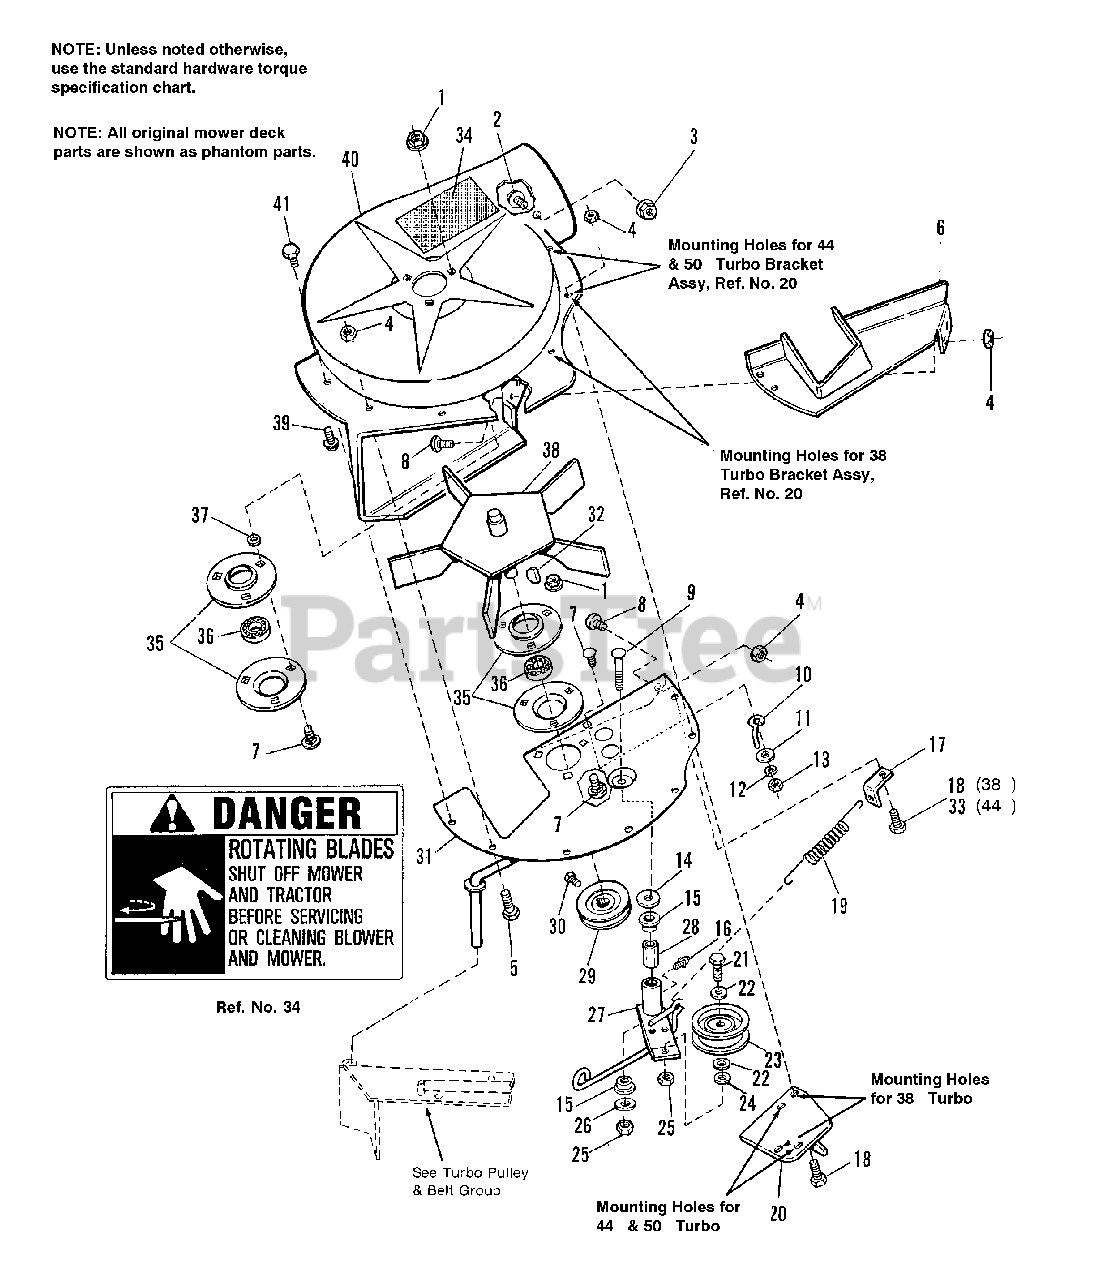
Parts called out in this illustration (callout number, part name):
1	NUT, Flange, Whizlock, 5/16-18
2	CARRIAGE BOLT, 1/4-20 x 5/8
3	NUT, Hex, Nylock, 1/4-20
4	NUT, Hex, Flange Lock, 1/4-20
5	CAPSCREW, Hex, 1/4-20 x 5/8
6	PLATE, Cover
7	CARRIAGE BOLT, 5/16-18 x 3/4
8	SCREW, Truss Hd., 1/4-18 x 5/8
9	CARRIAGE BOLT, 3/8-16 x 2-1/4
11	WASHER, Flat
12	WASHER, Spring Lock, 5/16
13	NUT, Hex, 5/16
14	WASHER, Flat
16	FITTING, Grease
17	BRACKET, Anchor, Spring
18	CAPSCREW, Hex Hd., 1/4-20 x 3/4
19	SPRING, Tension
20	BRACKET ASSY., Turbo
21	CAPSCREW, Hex Hd., 3/8-16 x 1-1/4
22	WASHER, Plain
23	IDLER PULLEY ASSY.
24	WASHER, Flat
25	NUT, Hex, Jam, Center Lock, 3/8-16
26	WASHER, Flat
27	LEVER ASSY, Turbo
29	PULLEY, Driven
30	SETSCREW, Hex, Socket Hd., 5/16-18 x 5/16
31	PLATE ASSY.
32	KEY, Woodruff, Modified
33	CAPSCREW, Hex Hd., 1/4-20 x 7/8
34	DECAL, Danger, Blower
35	BEARING, Retainer
37	PUSH NUT, 3/8
38	FAN ASSY., 5 Blade
39	SCREW, Truss Hd.., 1/4-18 x 1/4
40	FAN HOUSING
41	CAPSCREW, Hex, Taptite, 1/4-20 x 1/2
